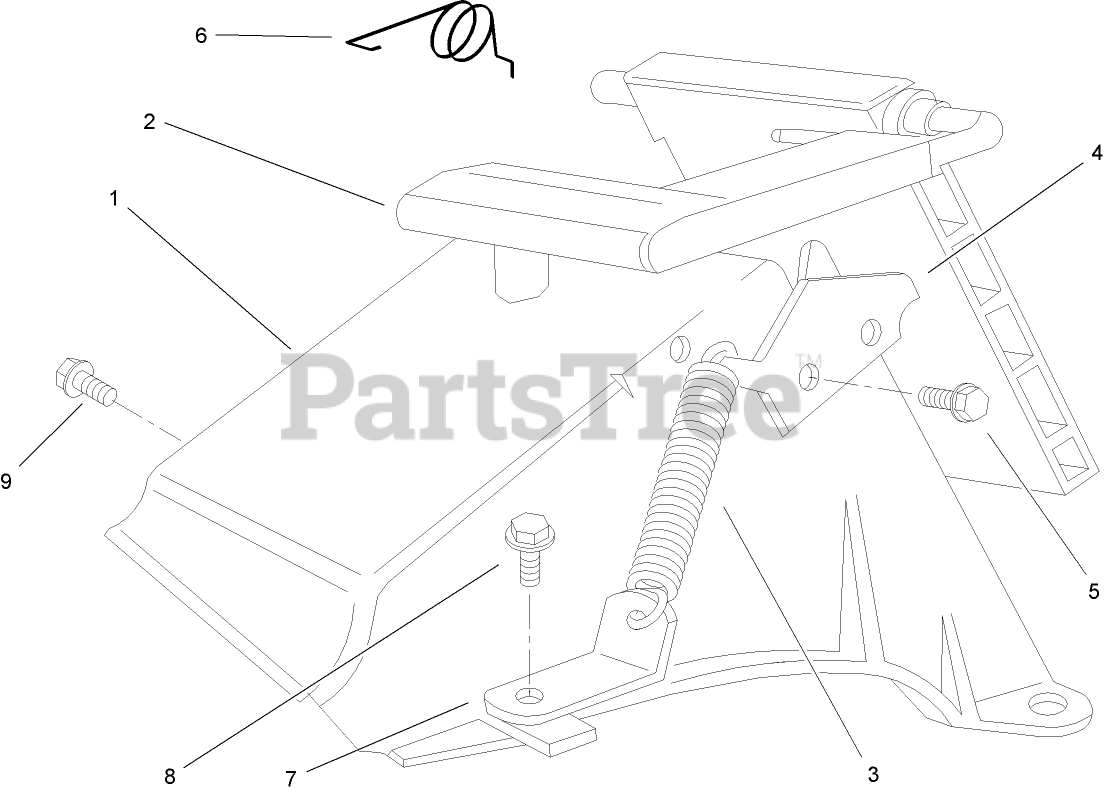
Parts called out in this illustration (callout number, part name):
1	TUNNEL-DISCHARGE
2	DISCHARGE DOOR ASM
3	SPRING-DOOR
4	LATCH-PLATE
5	SCREW-PLASTITE
6	RETAINER-DOOR
7	BRACKET-SPRING
8	SCREW AND WASHER ASM
9	SCREW-HWH
